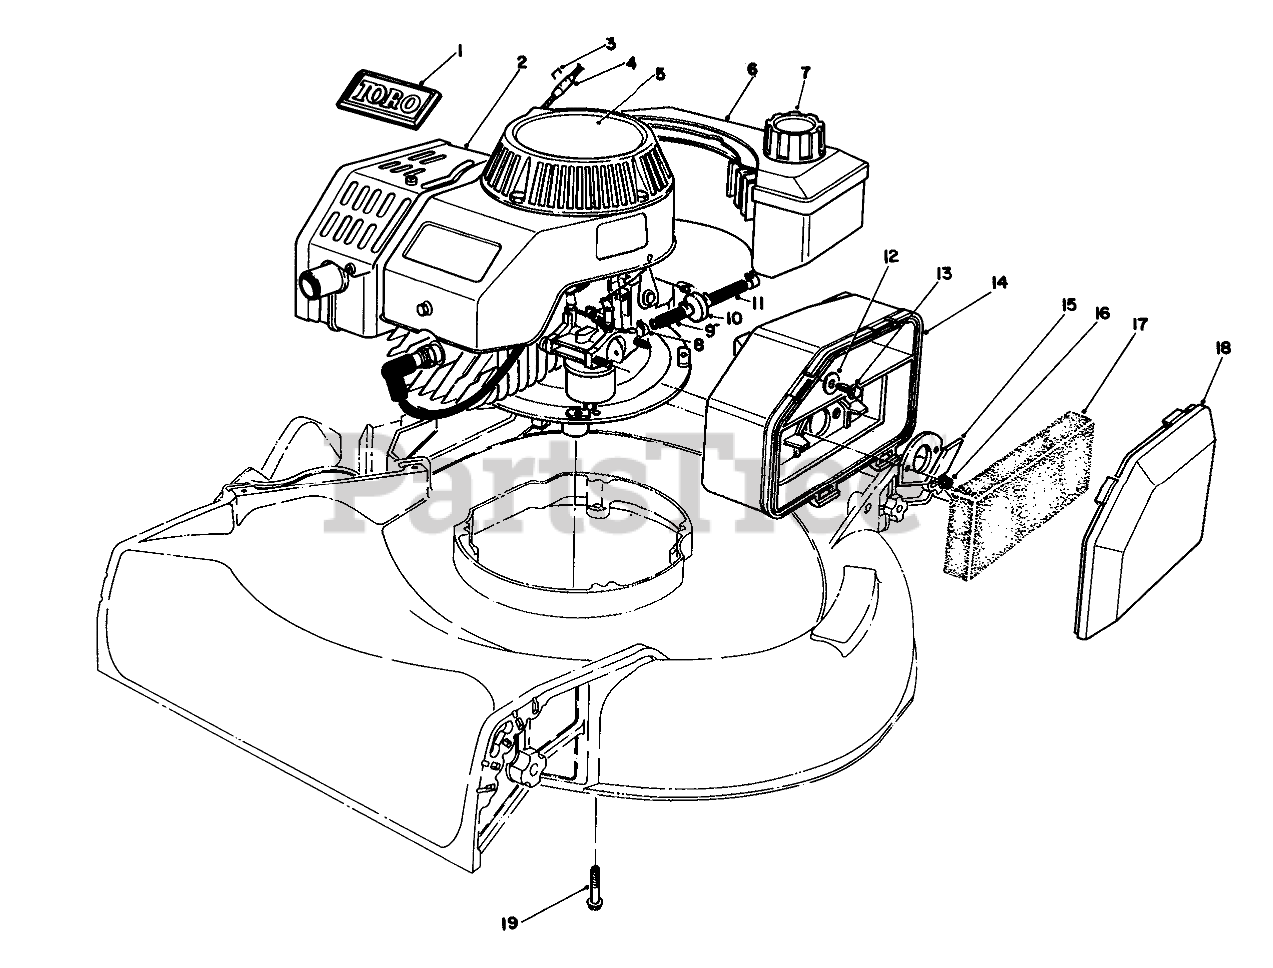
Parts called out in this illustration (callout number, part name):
1	TORO LOGO PLT
2	Engine
3	Staple
4	STOP-ROPE
5	DECAL
6	FUEL TANK ASM
7	GAS CAP ASM
8	CLAMP-FUEL LINE
9	HOSE-FUEL
10	FILTER-FUEL
11	HOSE-FUEL
12	WASHER-FLAT
13	SCREW-HH
14	AIR CLEANER
15	SPIT BACK DEFLECTOR
16	NUT-LOCK
17	FILTER
18	AIR CLEANER COVER
19	FLG SCREW,3/8-16X2.000
